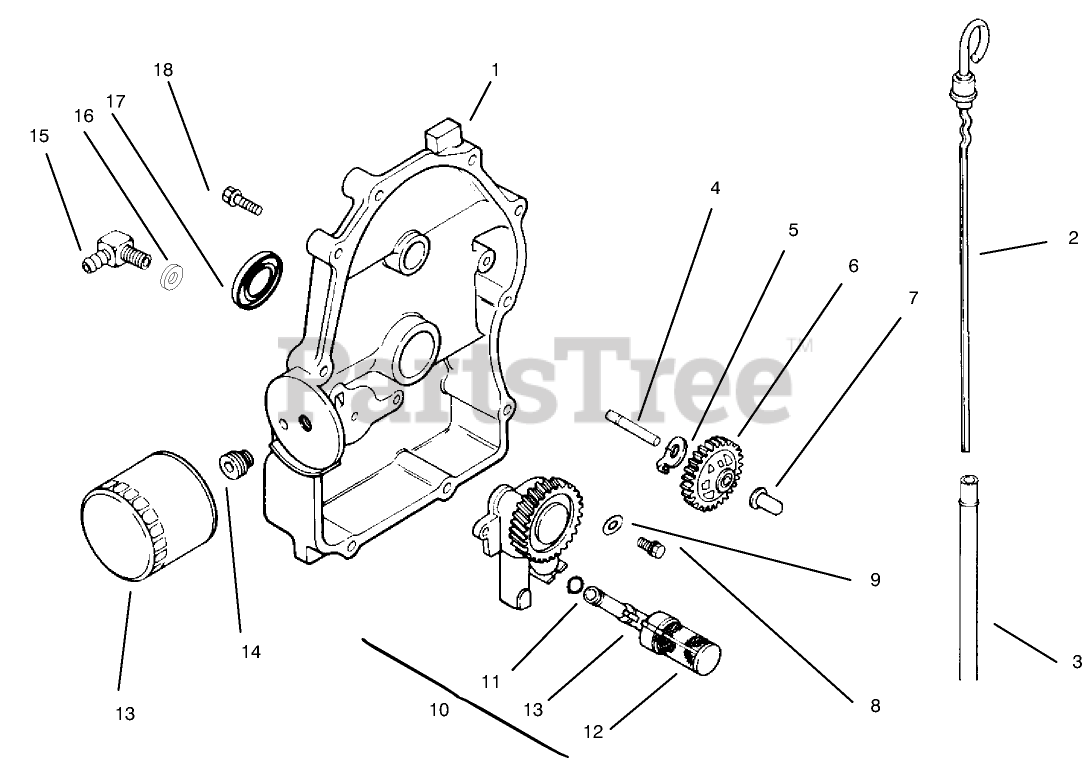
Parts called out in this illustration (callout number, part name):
1	Plate-Closure (Incl. Ref. #2-7, 10-12, 16 & 17)
2	Dipstick
3	Tube-Dipstick
4	SHAFT-GEAR, GOVERNOR
5	Tab-Locking
6	Kit-Governor Gear Asm (Incl. Ref. #7)
7	PIN-REGULATING, GOVERNOR
8	Screw
9	Washer-Flat
10	Oil Pump Assembly (Incl. Ref. # 11-12)
11	O-RING
12	Pick-up, Oil
13	FILTER-OIL
14	Nipple-Filter, Oil
15	Connector-Hose, 90 Deg
16	O-Ring
17	SEAL-OIL (P-T-O END)
18	Screw-HF (M8x1.25x45)
